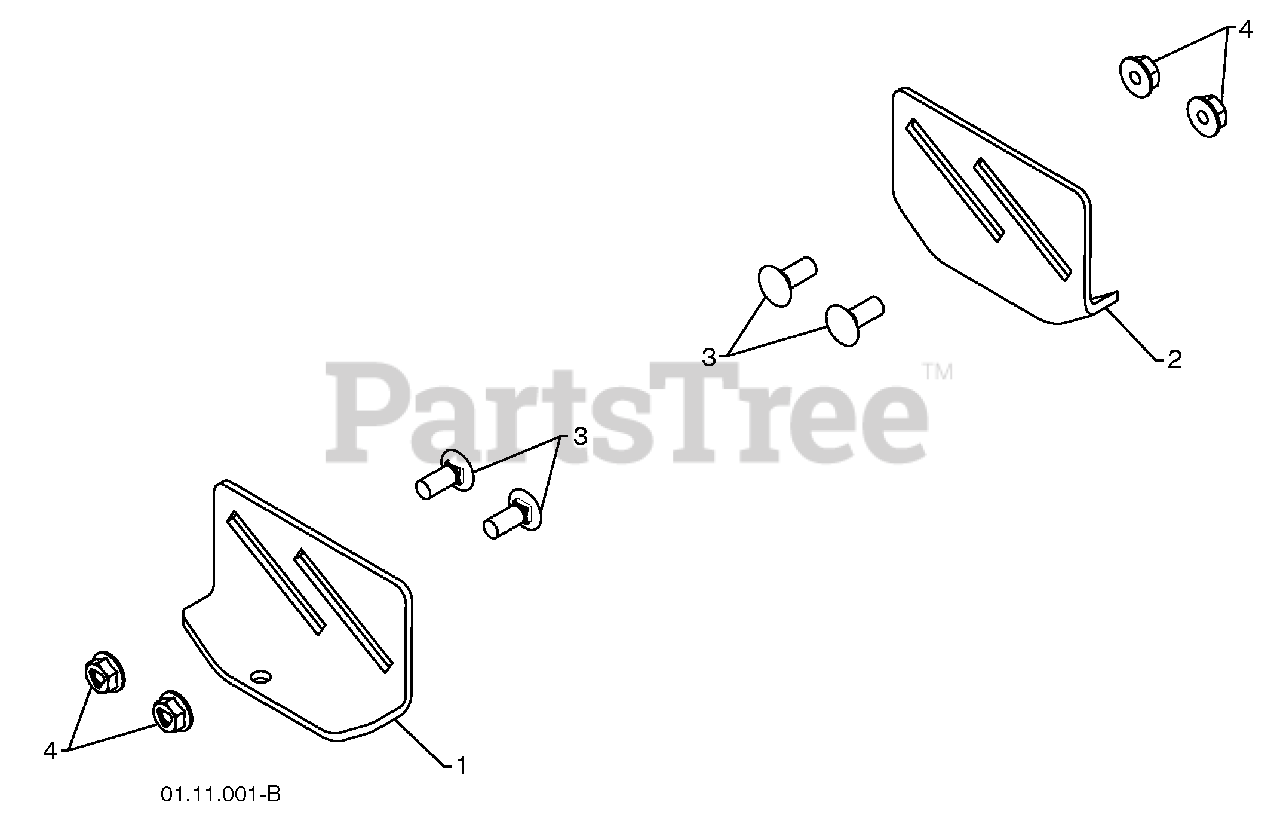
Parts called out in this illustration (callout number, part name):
1	SKID PLATE LH
2	SKID PLATE RH
3	CARRIAGE BOLT 5/16-18 X .75
4	NUT 5/16-18
